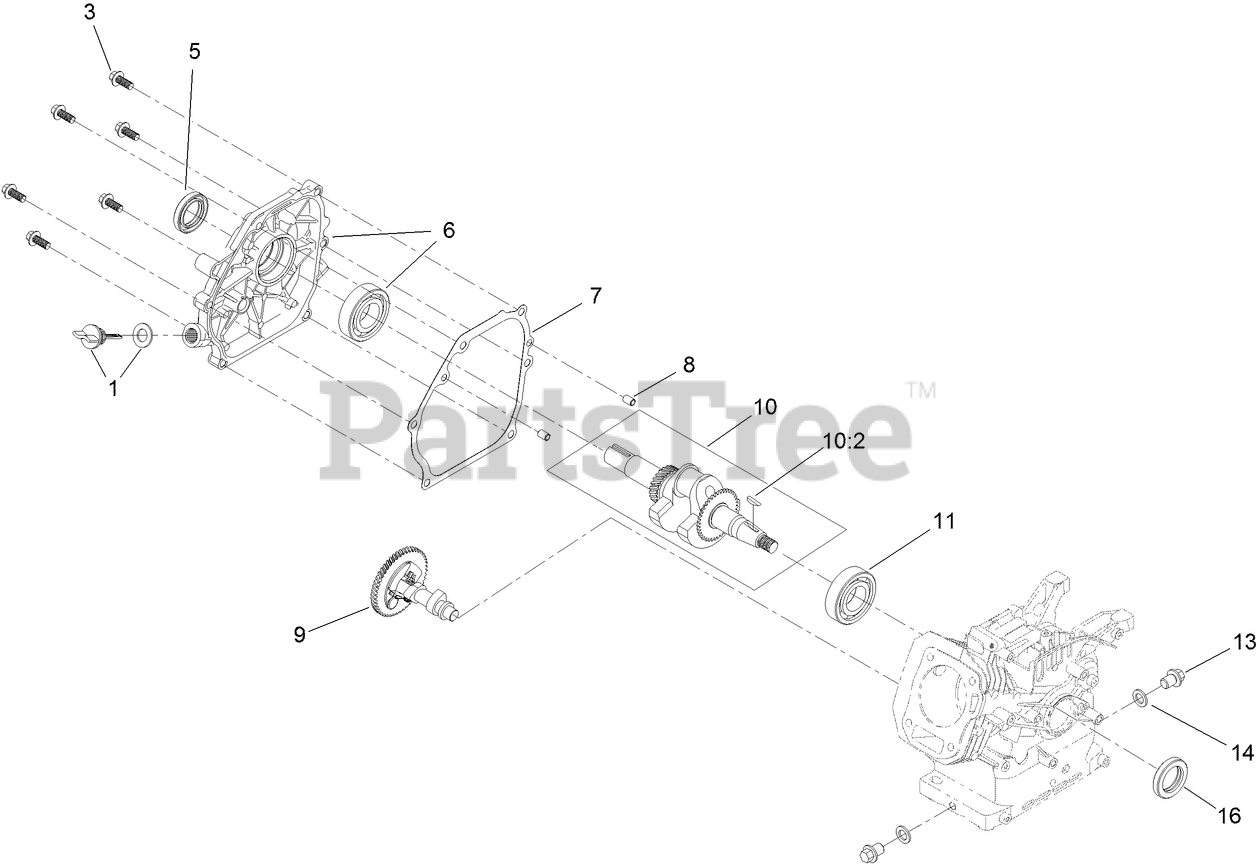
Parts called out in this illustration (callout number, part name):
1	DIPSTICK AND O-RING KIT
3	SCREW-HHF
5	SEAL-OIL
6	CRANKCASE COVER ASM
7	GASKET-COVER, CRANKCASE
8	PIN-DOWEL
9	CAMSHAFT
10	CRANKSHAFT ASM
10:2	KEY-WOODRUFF
11	BEARING-BALL
13	SCREW-HHF
14	WASHER-PLAIN
16	SEAL-OIL
